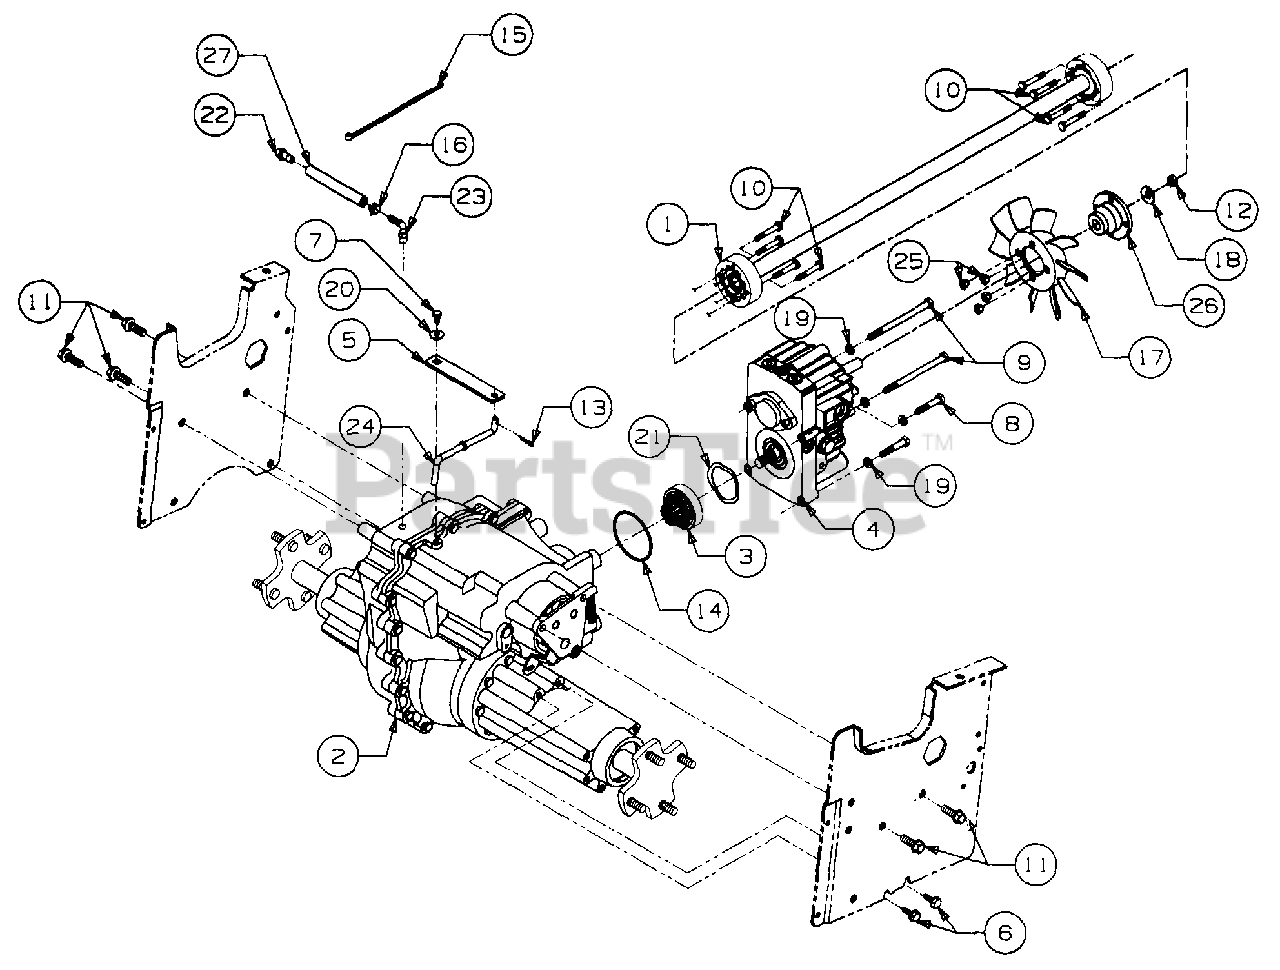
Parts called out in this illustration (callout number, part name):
1	Shaft Assy, Drive, 29.06 Lg
2	Transmission, Hydro
3	Pinion Assy, Input
4	Pump, Hydrostatic
5	Arm, Hydro Dump
6	Screw, Hex Wash Sf-Tapp 5/16-18 x.75 Lg
7	Screw, Hex Wash TT-Tapp, 1/4-20 x .75 Lg
8	Screw, Hex Cap, 5/16-18 x 1.75 Lg GR5
9	Screw, Hex Cap, 5/16-18 x 4.5 Lg GR5
10	Bolt, Hex Patch, 1/4-20 x 1.62 Lg GR5
11	Screw, Hex Wash Tapp 3/8-16 x 1.25 Lg
12	Nut, Hex Center Lock Jam 3/8-24
13	Pin, Internal Cotter, 5/16 Dia x 1.12 Lg
14	O-Ring, 2.75 x.103
15	Tie, Self-Clinch Cable
16	Clamp, Hose
17	Fan, 10 Blade Cooling
18	Washer, Bell, .380 x .88 x .062 Thk
19	Washer, Lock, 5/16
20	Washer, Bell, .265 x .75 x .062 Thk
21	Washer, Spring Wave, 1.96 x 2.44 x .06 Thk
23	Fitting, Elbow
24	Rod, Hydro Disengagement
25	Nut, Fan, 1/4-20
26	Adapter, Pump
27	Line, Fuel, 7 in. Lg
